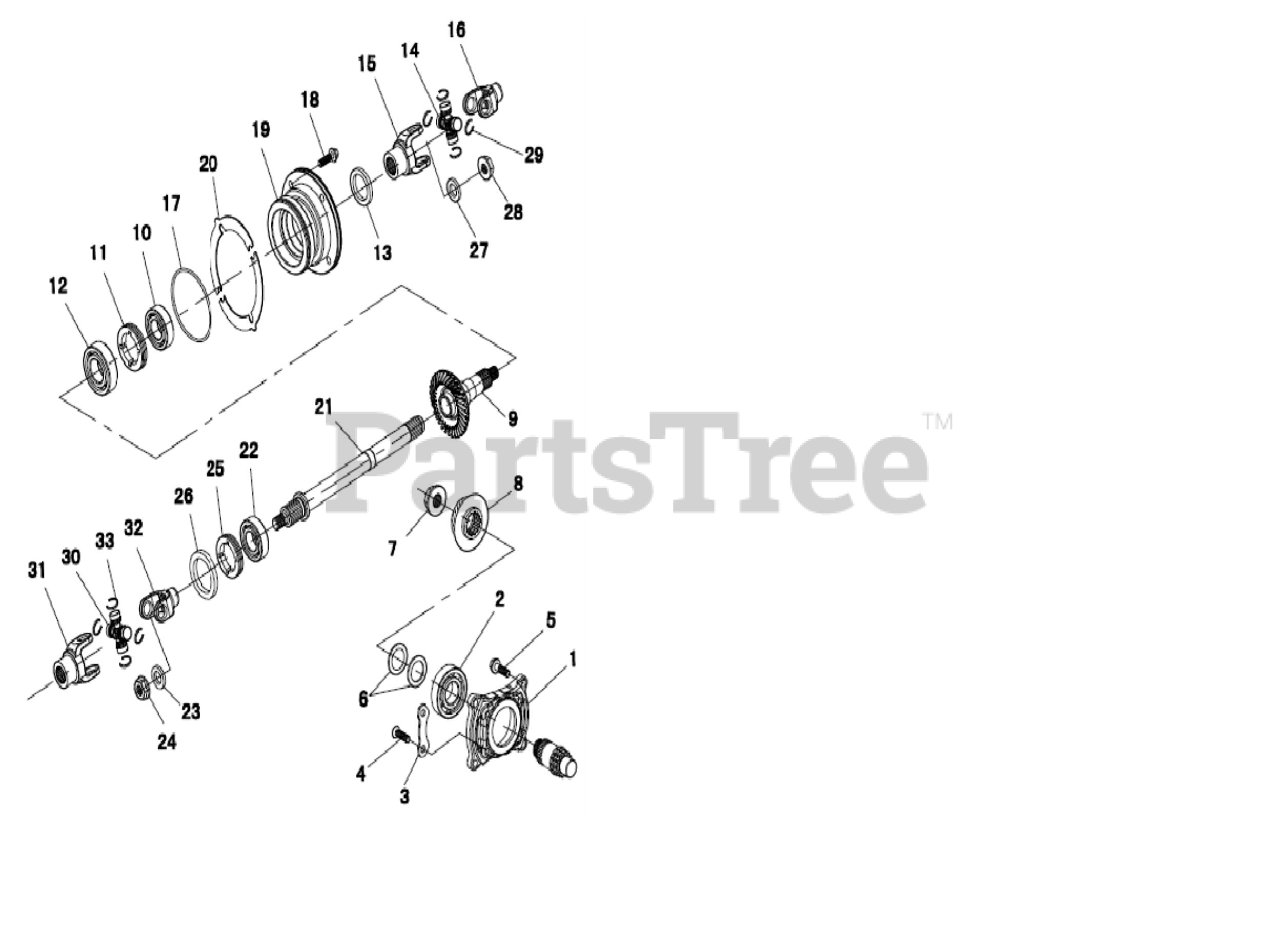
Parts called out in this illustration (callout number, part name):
1	X Shaft Bearing Block
2	Bearing 6305
3	Press Plate,X Shaft Bearing Block
4	Cross recessed countersunk head screw M8X25
5	Hex flange bolts M8X30
6	Spacer 26X38X0.4
7	Hex Flange Nut M22X1
8	Driving bevel gear
9	Driven bevel gear
10	Bearing 63/22
11	External thread nut M60X1.5
12	Bearing 6207
13	Oil Seal 30X46X8
14	Criss-Cross Shaft
15	U-joint A(?22?
16	U-joint B(?22?
17	O-Ring 88X2.8
18	Hex head bolt & plain washer assemblies M8X30
19	Y Shaft Bearing Block
20	Spacer 0.1,Bevel Gear
21	Y Driveshaft
22	Bearing 6205
23	Washer 14.5X32X5
24	Self-locking Nut M14X1.5
25	External thread nut M55
26	Oil Seal 44X60X7
27	Washer 16.5X28X4
28	Self-locking Nut M16X1.5
29	Grip Ring ?22
30	Criss-Cross Shaft
31	U-joint B(?22?
32	U-joint A(?22?
33	Grip Ring ?22
